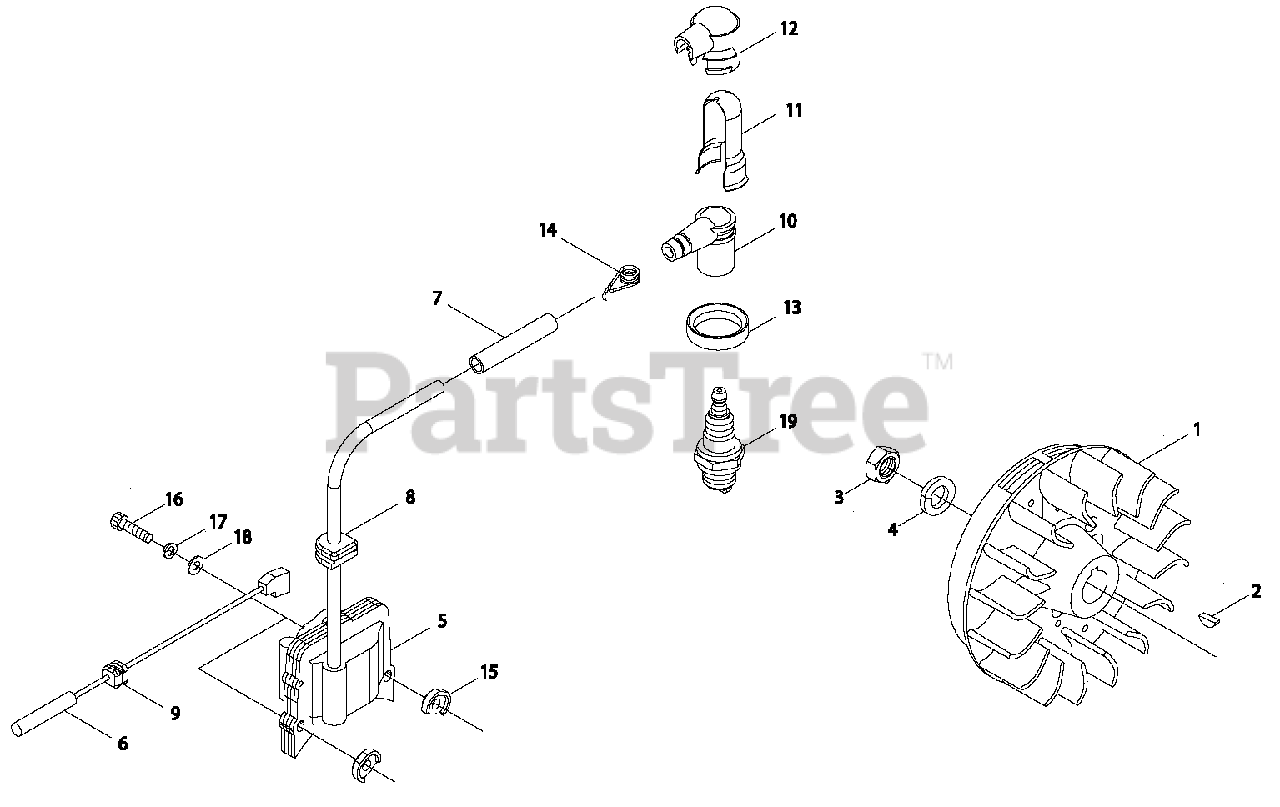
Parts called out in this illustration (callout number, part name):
1	FLYWHEEL
2	KEY, WOODRUFF 3×10
3	NUT 10×1.25
4	WASHER, SPRING 10
5	COIL, IGNITION
6	LEAD - IGNITION
7	TUBE, INSULATOR
8	GROMMET
9	GROMMET, LEAD
10	CAP, SPARK PLUG
11	SHIELD
12	COVER, CAP
13	SEAL, SPARK PLUG
14	TERMINAL, SPARK PLUG
15	COLLAR 4
16	BOLT M4×24
17	WASHER, SPRING 4 MM
18	WASHER 4.3×9.6×0.8
19	SPARK PLUG - BMR6A
